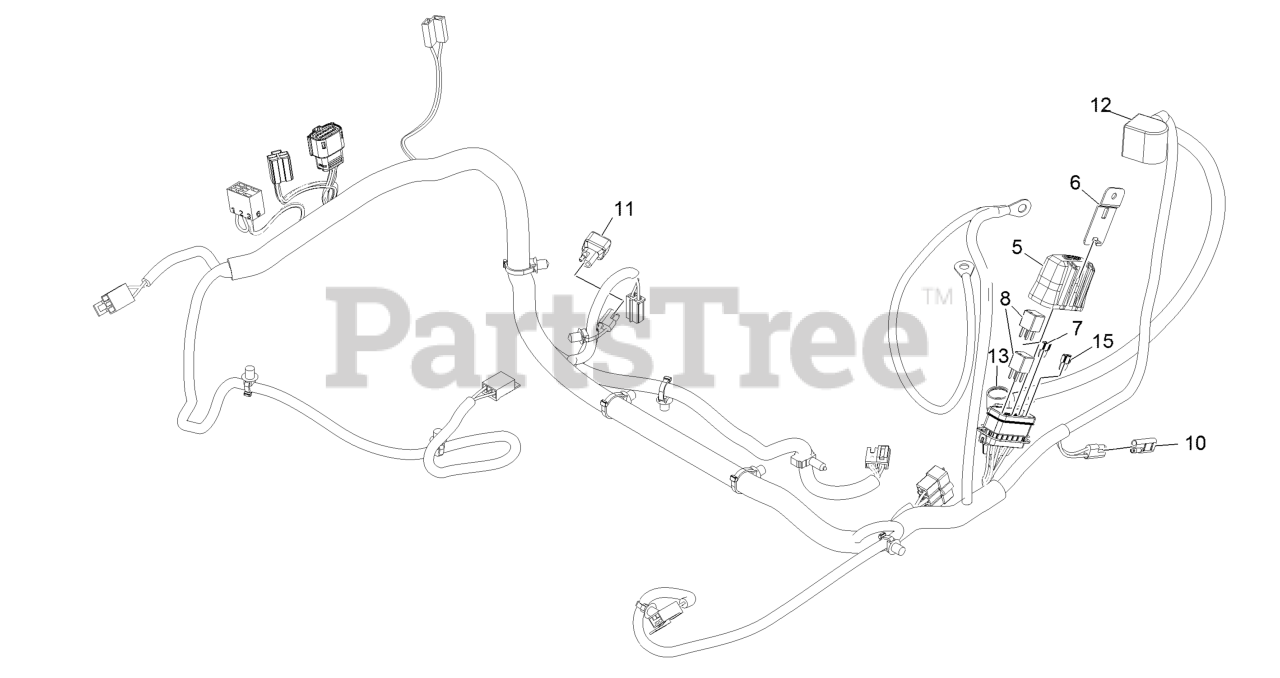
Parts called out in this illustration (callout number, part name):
5	Cover-Block, Fuse
6	Clip-Mounting
7	Fuse-Mini Blade, 20 Amp
8	Relay-Micro
10	Cap-Plug
12	Insulator-Battery
13	Insulator-Solenoid
15	Fuse-Mini Blade, 15 Amp
